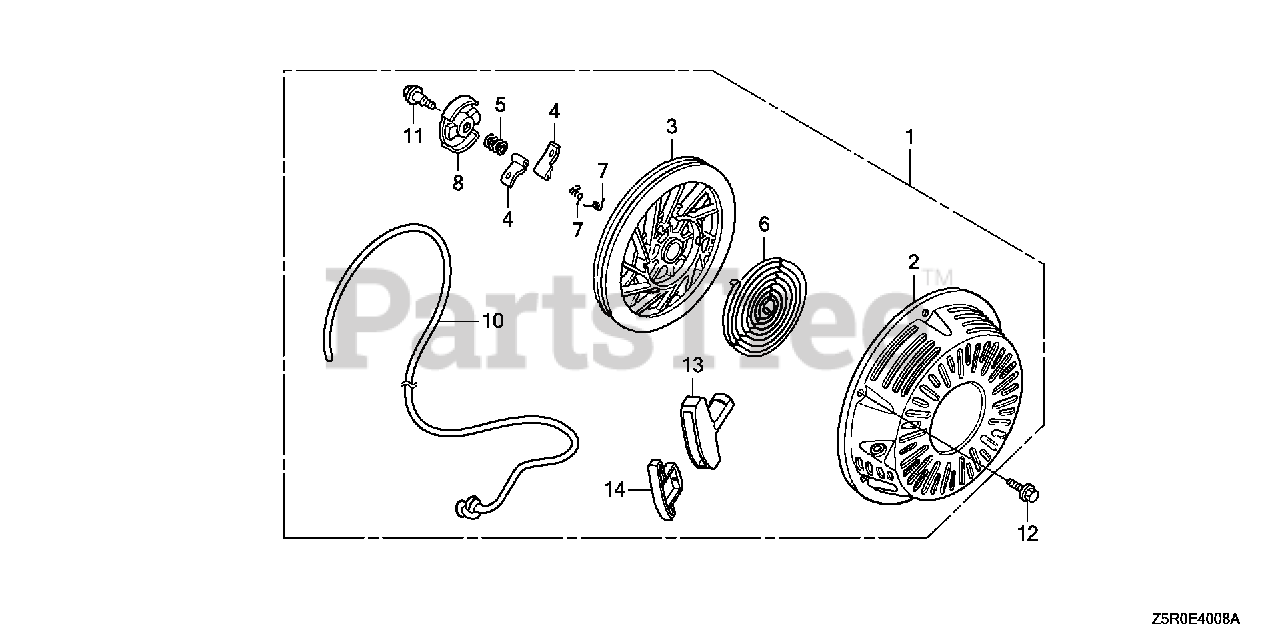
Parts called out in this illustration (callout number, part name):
1	STARTER ASSY., RECOIL *NH1* (BLACK)
1	STARTER ASSY., RECOIL *NH1* (FOR U.S.A.) (BLACK)
2	CASE, RECOIL STARTER *NH1* (BLACK)
3	PULLEY, RECOIL STARTER
4	RATCHET, STARTER
5	SPRING, FRICTION
6	SPRING, STARTER RETURN
7	SPRING, RATCHET
8	RETAINER, SPRING
9	GRIP, STARTER
10	ROPE, RECOIL STARTER
11	SCREW, CENTER
12	BOLT, FLANGE (6X10)
13	GRIP, STARTER (COO)(FOR U.S.A.)
14	GRIP, REINFORCEMENT
